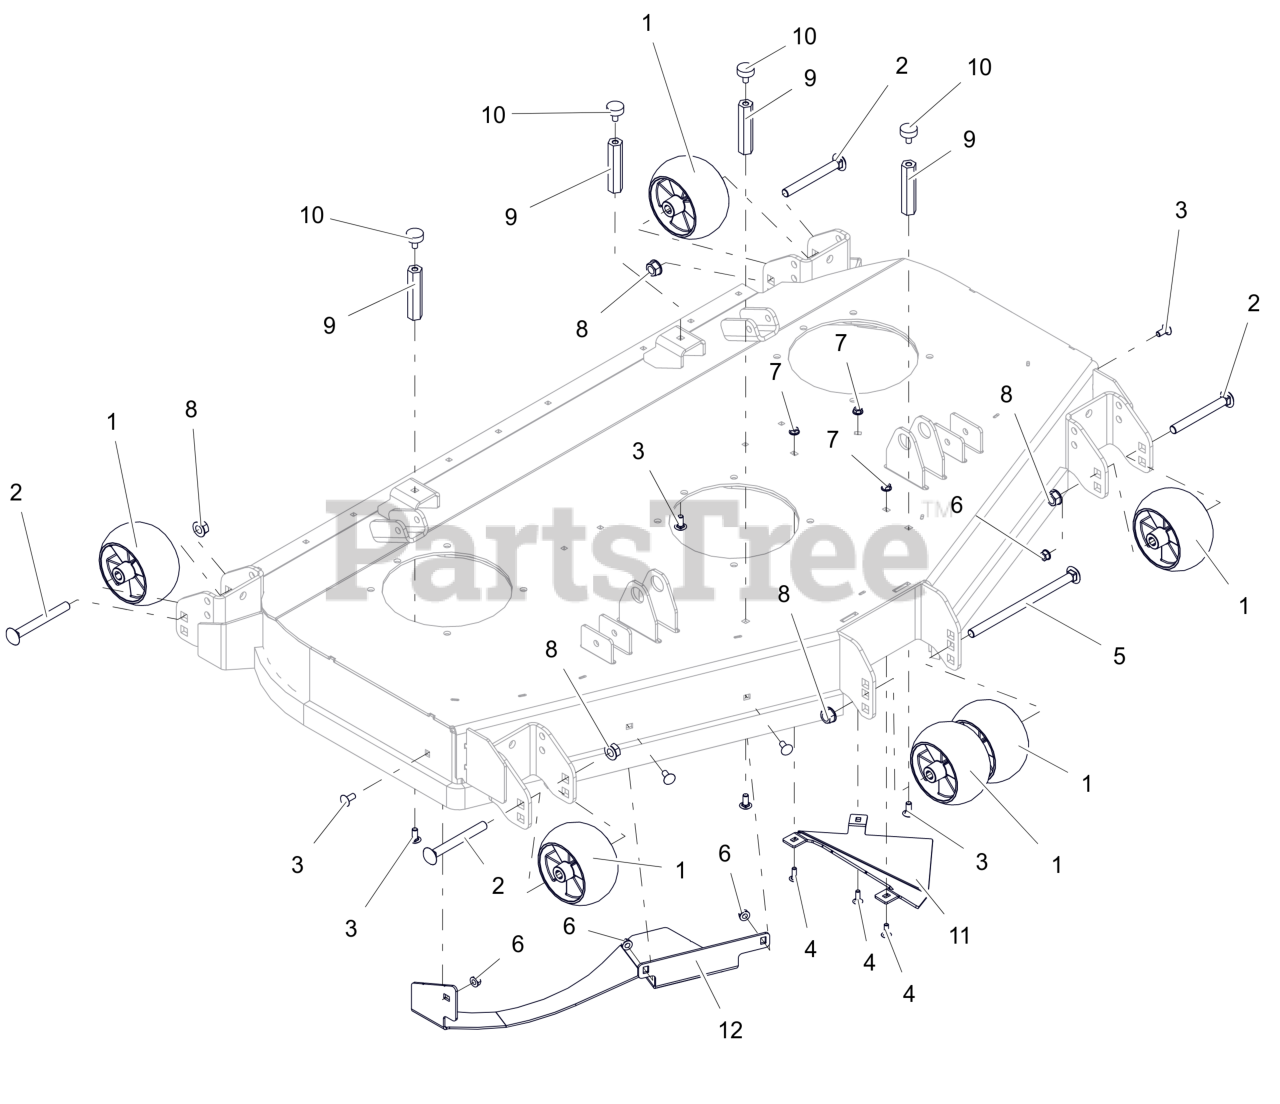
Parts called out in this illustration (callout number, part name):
1	WHEEL, ANTI SCALP - 5X3 CTR W/RIBS
2	BLT,RHSN .50-13X4.50 G5 ZCC
3	BLT, RHSSN.31-18X.750 G5 ZCC
4	BLT, RHSN .25-20X.750 G5 ZCC
5	BTL,RHSN .500-13 X 8.5S G5 ZCC
6	NUT,LK-CTR-FLG .31-18 GF ZCC
7	NUT-LK-CTR-FLG .25-20 ZC120
8	NUT-LK-CTR-FLG .500-13 GG ZCC
9	NUT, COUPLING .312-18 X 3.375
10	BUMPER, RUBBER
11	BAFFLE- 52" TRIANGLULAR INSERT
12	DEFLECTOR- 52" BOLT-IN BAFFLE
